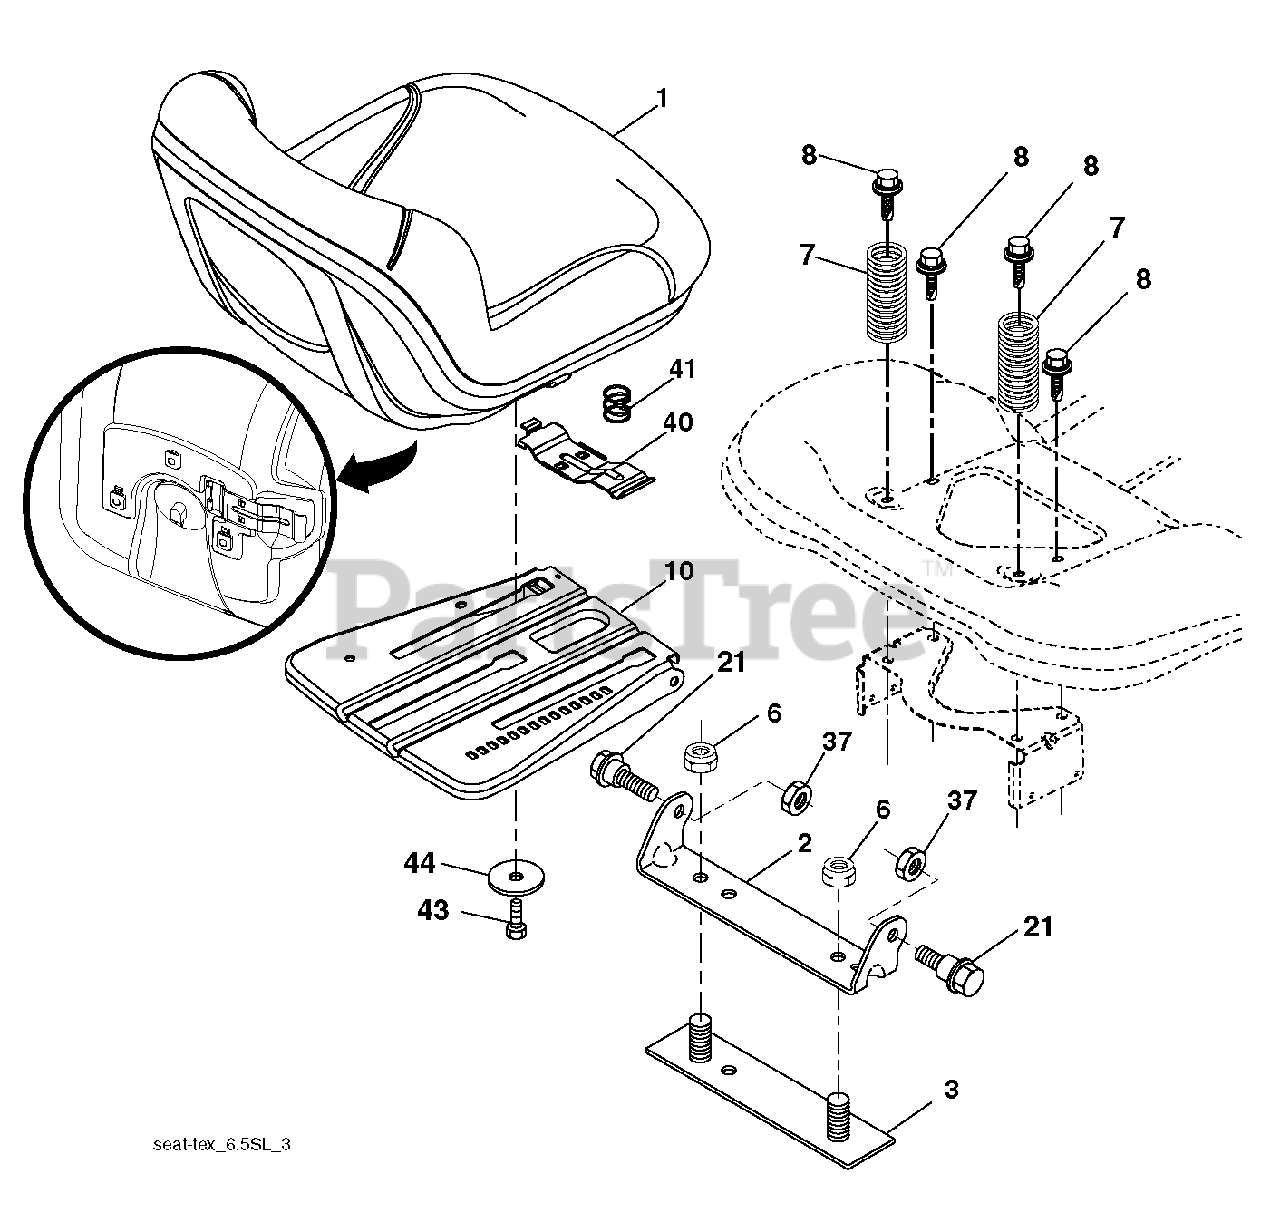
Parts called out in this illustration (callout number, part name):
1	SEAT.TH130.GREY.HUSQ.TEX
2	BRKT.PIVOT.FENDER
3	STRAP
6	NUT
7	SPRING COMPRESSION
8	BOLT, 5/16-18 X 1 3/4
10	PAN.ASM.SEAT.3PT
21	BOLT.SHOULDER.5/16-18
37	NUT.71038.31-18.HEX.NYLOCK
40	HANDLE.SLIDE.SEAT.TEX.BLACK
41	SPRING.LATCH.SEAT.TEX
44	WASHER 13/32 X 2-3/8 X 12GA
